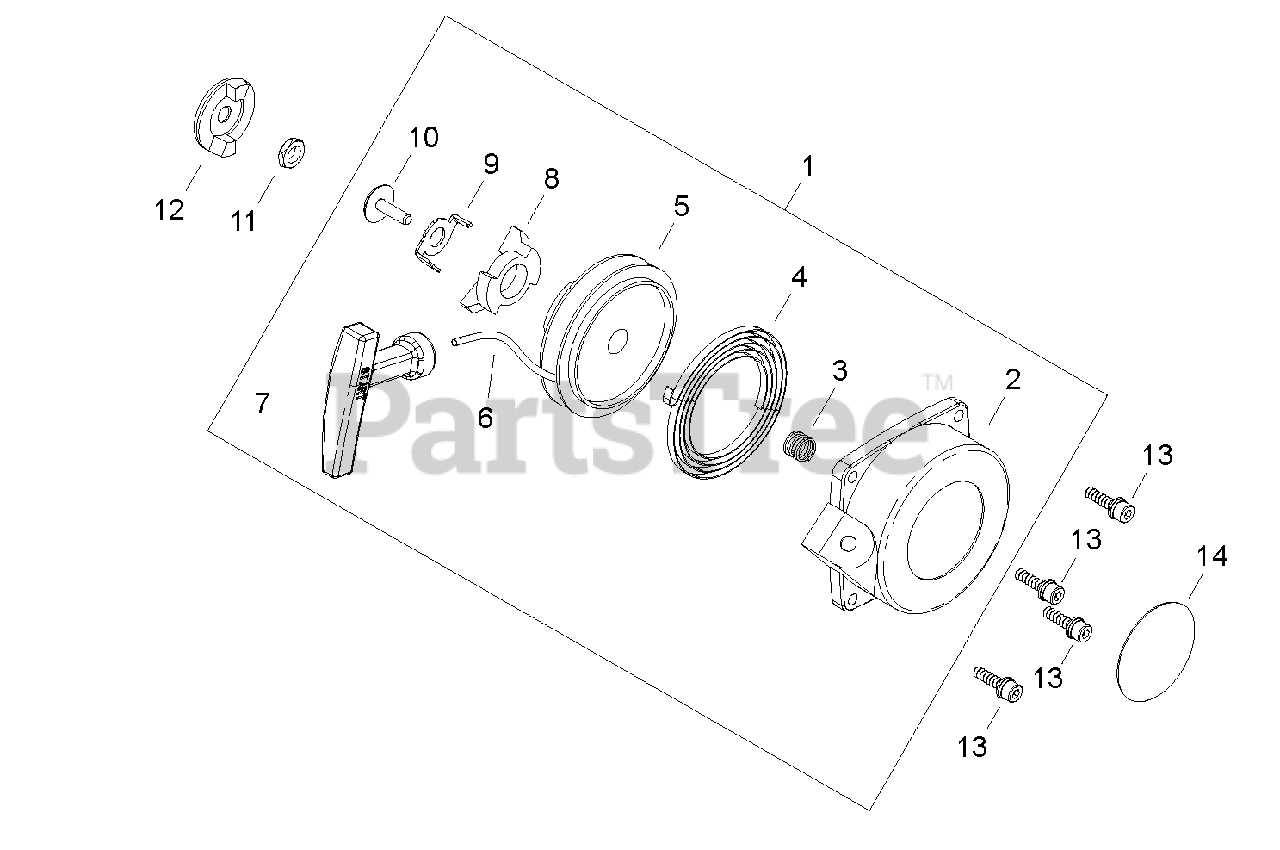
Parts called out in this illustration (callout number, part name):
1	STARTER ASSY
2	CASE, STARTER
3	SPRING, BRAKE
4	SPRING, REWIND
5	REEL, ROPE
6	ROPE, STARTER
7	GRIP, STARTER
8	PAWL, STARTER
9	RETAINER
10	SCREW
11	NUT - 8
12	REEL, ROPE
13	SCREW - 5X20
14	LABEL - C4
